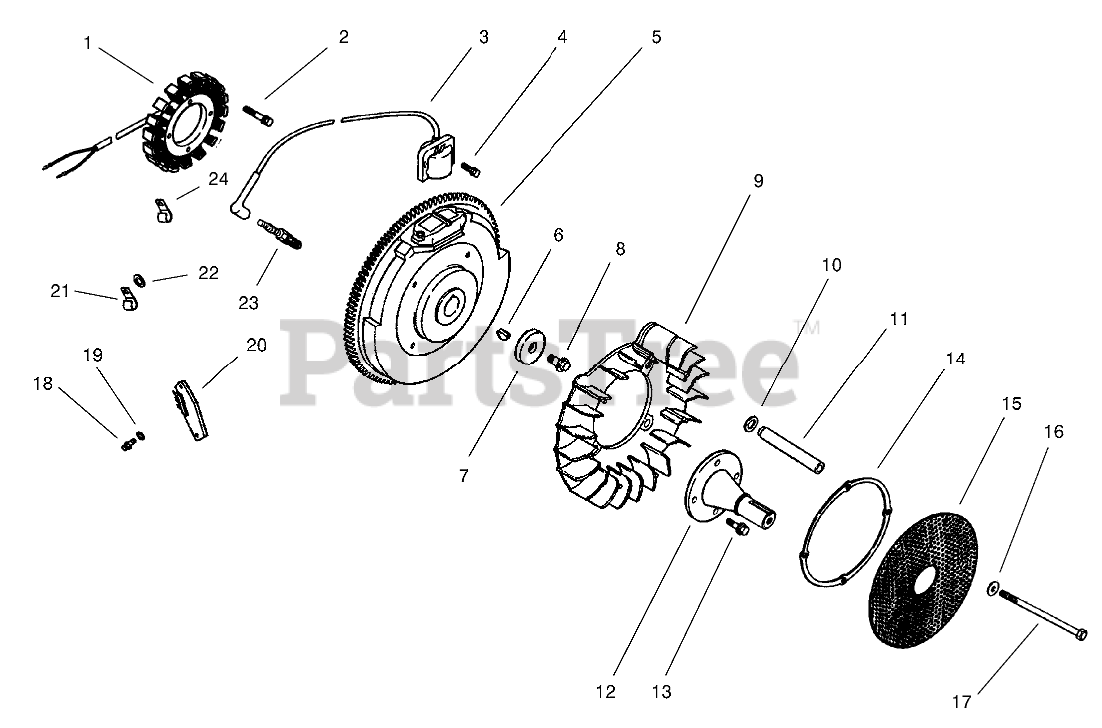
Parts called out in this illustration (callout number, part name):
1	Kit, 15 amp stator (Incl. 24 126 71 bracket)
2	Screw
3	Module-Ignition
4	Screw
5	Flywheel
6	Key
7	Washer
8	Screw
9	Fan
10	Washer, sping
11	Spacer
12	Shaft, front drive
13	Screw
14	Ring-Support
15	Screen-Grass
16	Washer
17	Screw-Hex
18	Screw
19	Washer
20	Rectifier-Regulator
21	Clip
22	Washer
23	Plug-Spark
24	Clip
